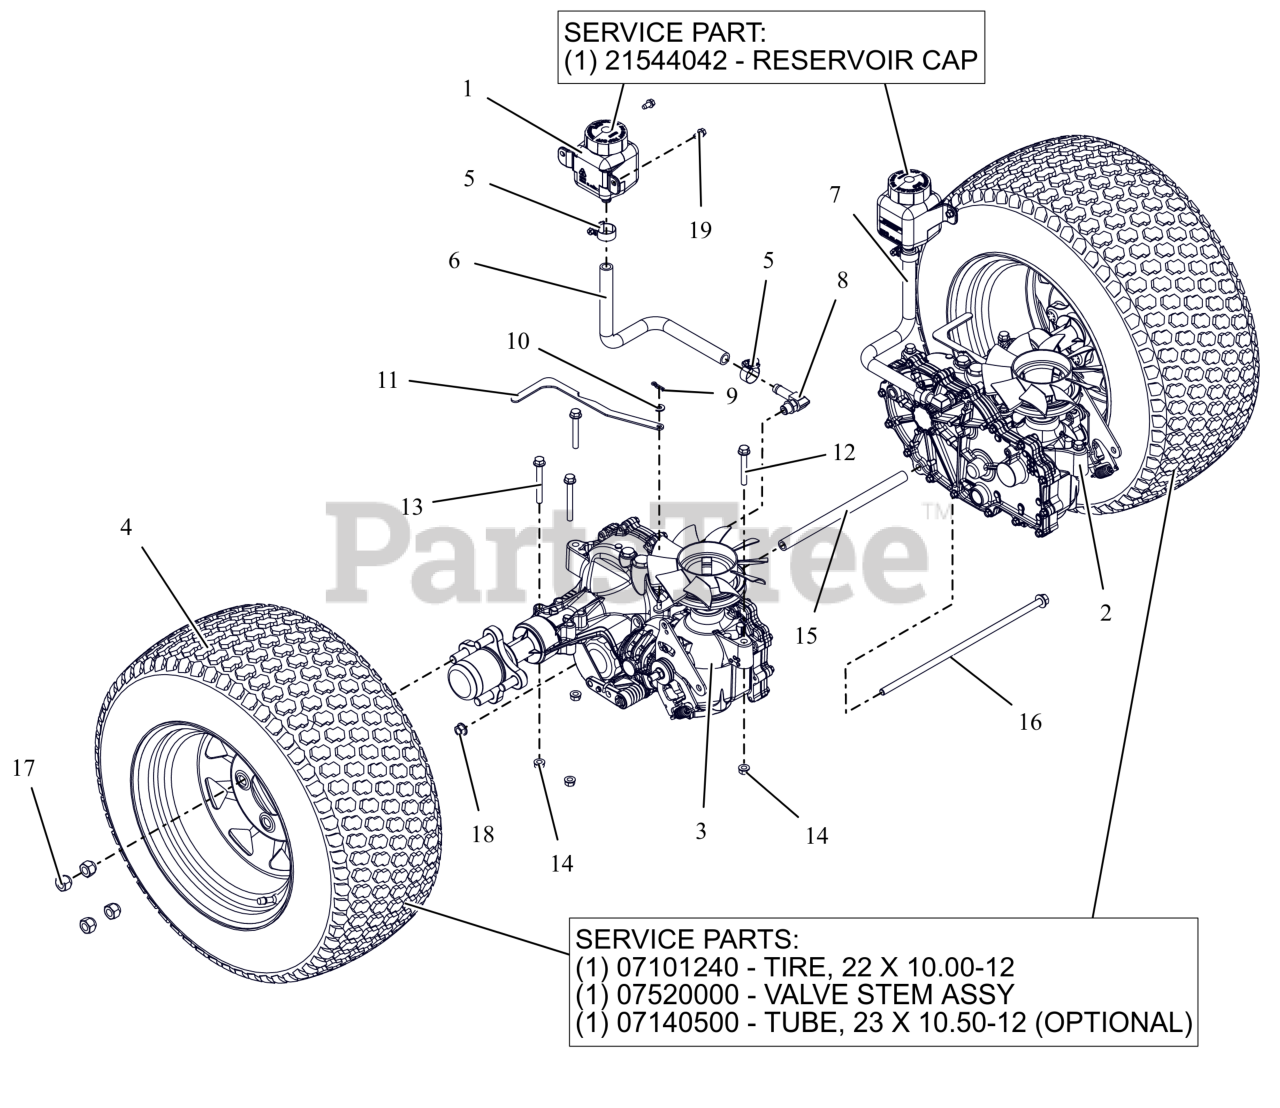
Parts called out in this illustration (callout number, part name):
1	TANK, EXPANSION
1	CAP, HYDRO RESERVOIR REPLAC.
2	TRANSAXLE, ZT3100 - LH
3	TRANSAXLE, ZT3100 - RH
4	ASM-WHL/TIRE 22X10-12 LG BLK
4	TIRE, 22X10.00-12
4	VALVE STEM ASS'Y
4	TIRE TUBE 22,23,24/8.50/9.50/10.00/10.50/12.00-12 4 PLY TR13 STRAIGHT VALVE
5	CLAMP,.88 DIA. HOSE
6	HOSE, FORMED EXPANSION -HD RH
7	HOSE, FORMED EXPANSION -HD LH
8	FITTING, HYD (90 DEG)
9	PIN, HAIR #225 .072X1.09
10	WSHR,FLT .281X.625X.065 ZCC
11	BRKT, VALVE DUMP
12	BLT,HEX-FLG .31-18X2.25 G5 ZCC
13	BLT,HEX-FLG .31-18X2.75 G5 ZCC
14	NUT,LK-CTR-FLG .31-18 GF ZCC
15	SPCR,TRANS. .406IDX.63ODX9.95L
16	BLT,HEX-FLG .38-16X13 G5 ZCC
17	NUT, WHEEL .50-20 ZCC
18	NUT-LK-TOP-FLG .38-16 ZC120
19	SCR-TAP .25-20X.50 HWH ZCC
